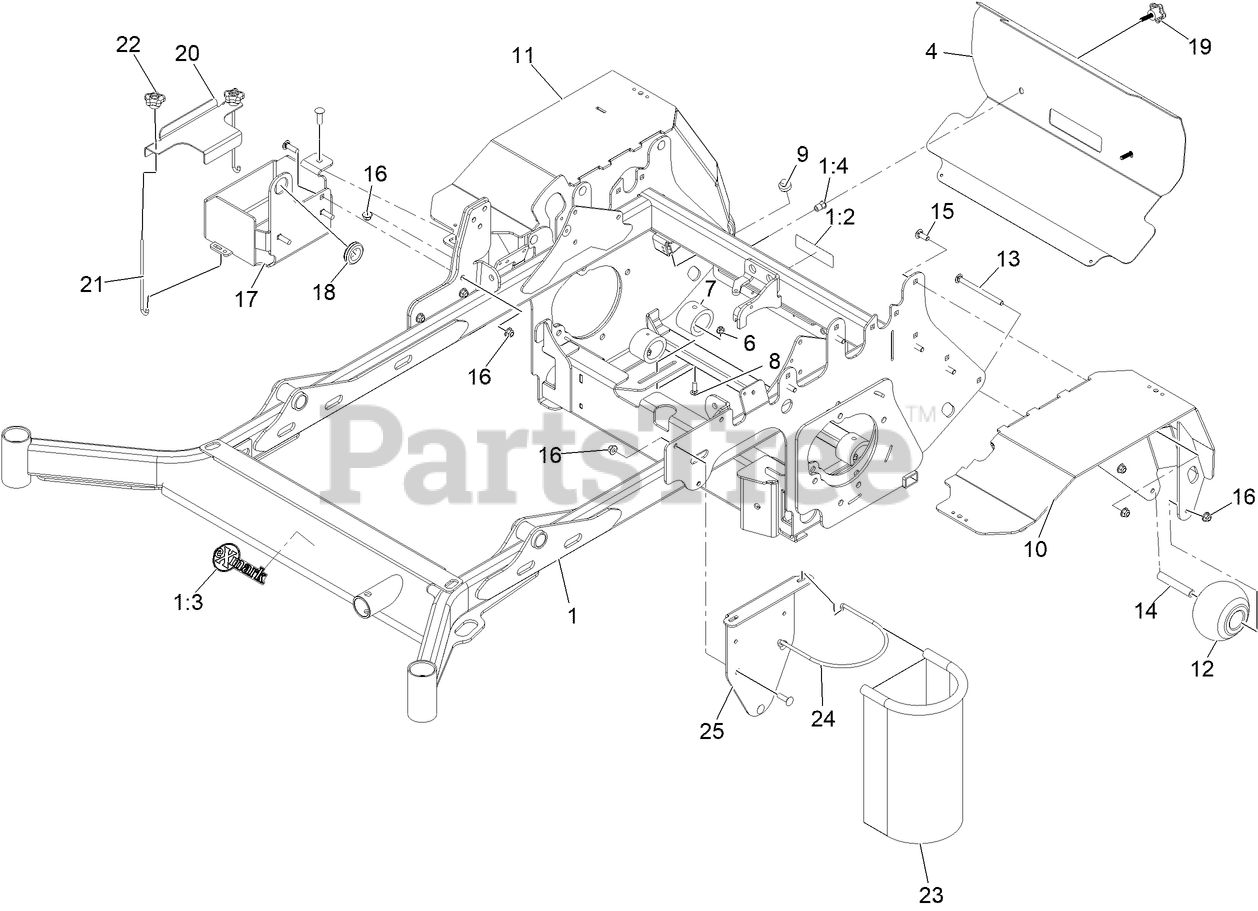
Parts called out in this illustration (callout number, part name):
1	ASM-Frame Stand On 72
1:2	DECAL-COVER, MISSING
1:3	DECAL-EXMARK LOGO
1:4	NUT-CLINCH
4	GUARD-REAR FOOT
6	NUT-HF, NI
7	BUMPER-ISOLATOR
8	BOLT-CARR
9	BUMPER-RUBBER
10	FENDER-LH WELDT
11	FENDER-RH WELDT
12	ROLLER-SCALP, ANTI
13	BOLT-CARR
14	SPACER- ROLLER
15	SCREW-CARR
16	NUT-HF, NI
17	BATTERY TRAY
18	GROMMET
20	BRACKET-BATTERY HOLD DOWN
21	BOLT-HOLDDOWN
22	KNOB-HANDLE
23	BAG-TRASH
24	ROD-BAG, TRASH
25	BRACKET-TRASH BAG MOUNT
